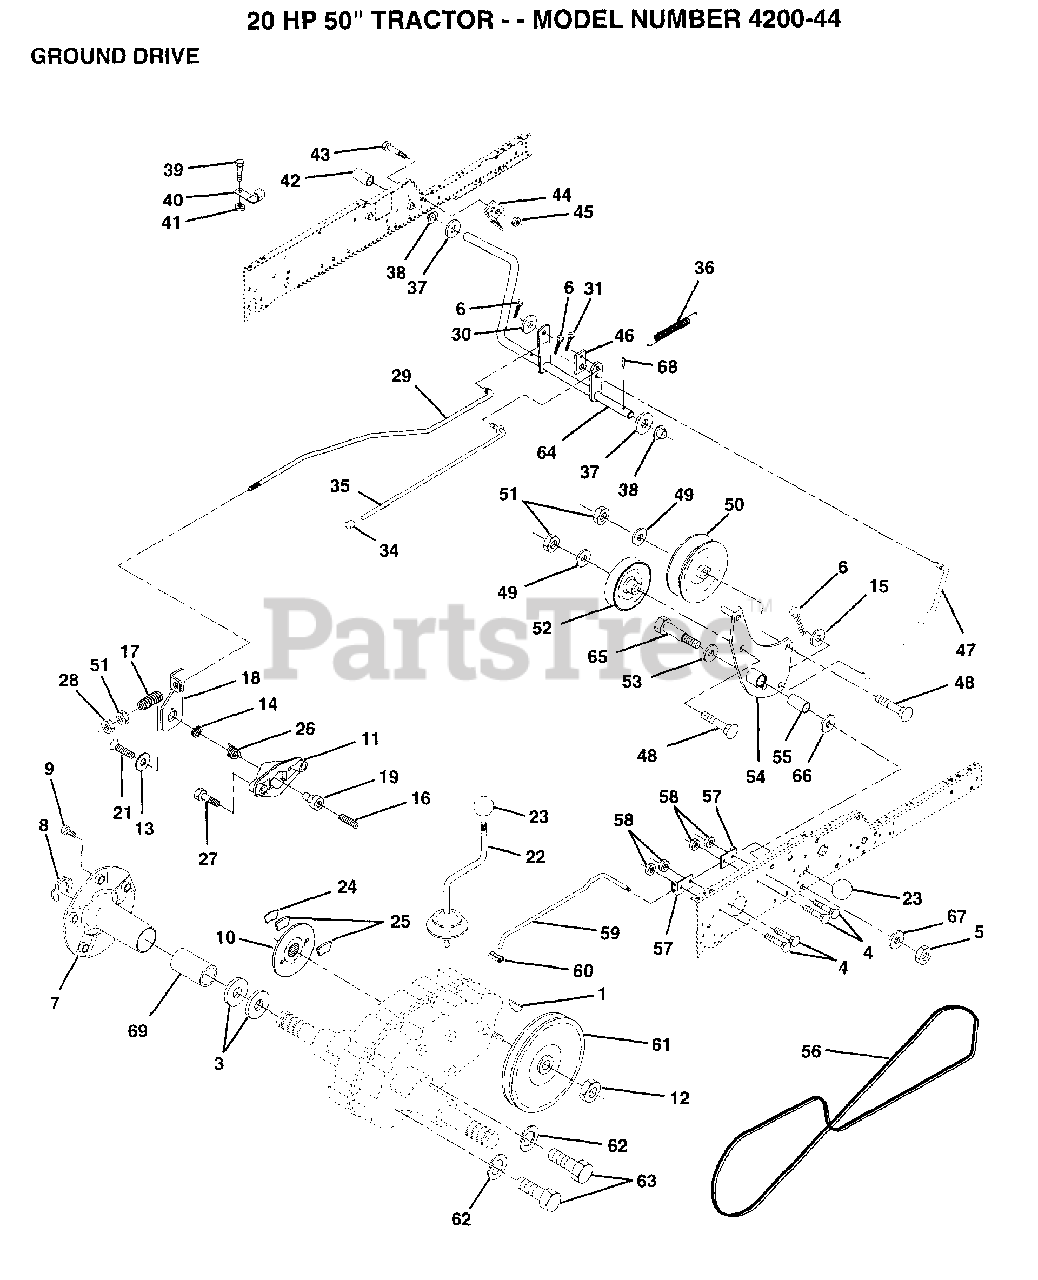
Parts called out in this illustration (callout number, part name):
3	WASHER T
4	BOLT
6	COTTER PIN
8	KLIP RING
9	BOLT.HUB.WHL.REAR
11	YOKE BRAKE DISC
12	NUT STD
13	WASHER SPECIAL
14	BUSHING LEVER BKT
15	WASHER
16	SCREW SET 1/4-20
17	"SPRING,ROD BRAKE"
18	LEVER BRAKE GT
19	CAM BRAKE DISC GT
21	SCREW FLT 1/4X28
22	GEAR SHFT LVR T
23	KNOB
24	SUPPORT PUCK BRKE
25	PUCK BRAKE TOP
26	SPRING RET BRAKE
27	SCREW HX WASH
28	NUT
29	ROD BRAKE ZINC GT
30	WASHER
34	PLUNGER CAP T
35	ROD BRAKE PART GT
37	WASHER
38	NYLINER T
39	SCREW
40	ACT-SWITCH T
42	PEDAL COVER T
43	BOLT LT
44	BRKT SWITCH GT
45	NUT
46	RETAINER SPRING
47	ROD.CLUTCH
48	BOLT
49	WASHER
50	FLAT IDLER PULLEY
51	NUT
52	PULLEY.IDLER.V.GR
53	WASHER T
54	ARM.ASM.IDLER.CLU
55	"LY, BEARING"
56	BELTV.GR.DR.83.
57	ROD BRACKET GT
58	NUT
59	ROD SHIFT HI LO
60	CONNECTING LINK
62	LOCKWASHER
63	BOLT
65	AXLE BOLT
66	WASHER.HARD.BLADE
67	WASHER
68	ROLL PIN STD
69	"COVER, HUB"
